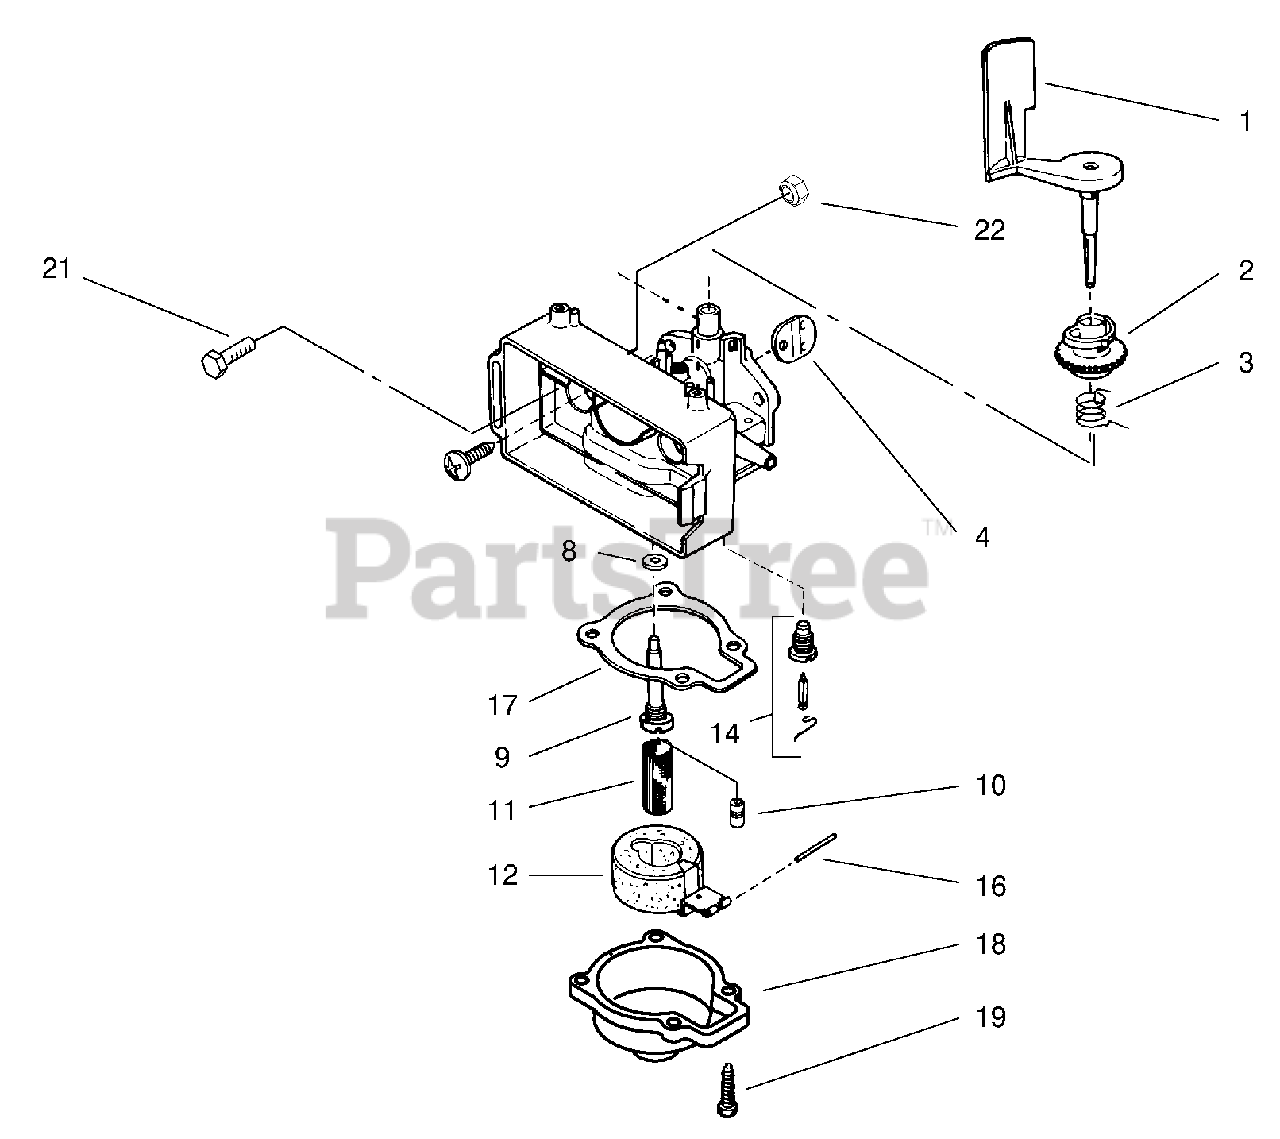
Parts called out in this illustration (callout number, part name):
1	Airvane and Shaft
2	Collar-Adjust, Airvane
3	Spring-Throttle
4	Disc-Throttle
10	Jet-Main
11	Filter-Fuel
12	Float & Arm ASM
14	Valve/Seat-Float
16	Pin-Straight
18	Chamber-Float
19	Screw-HH
22	Nut-Hex
